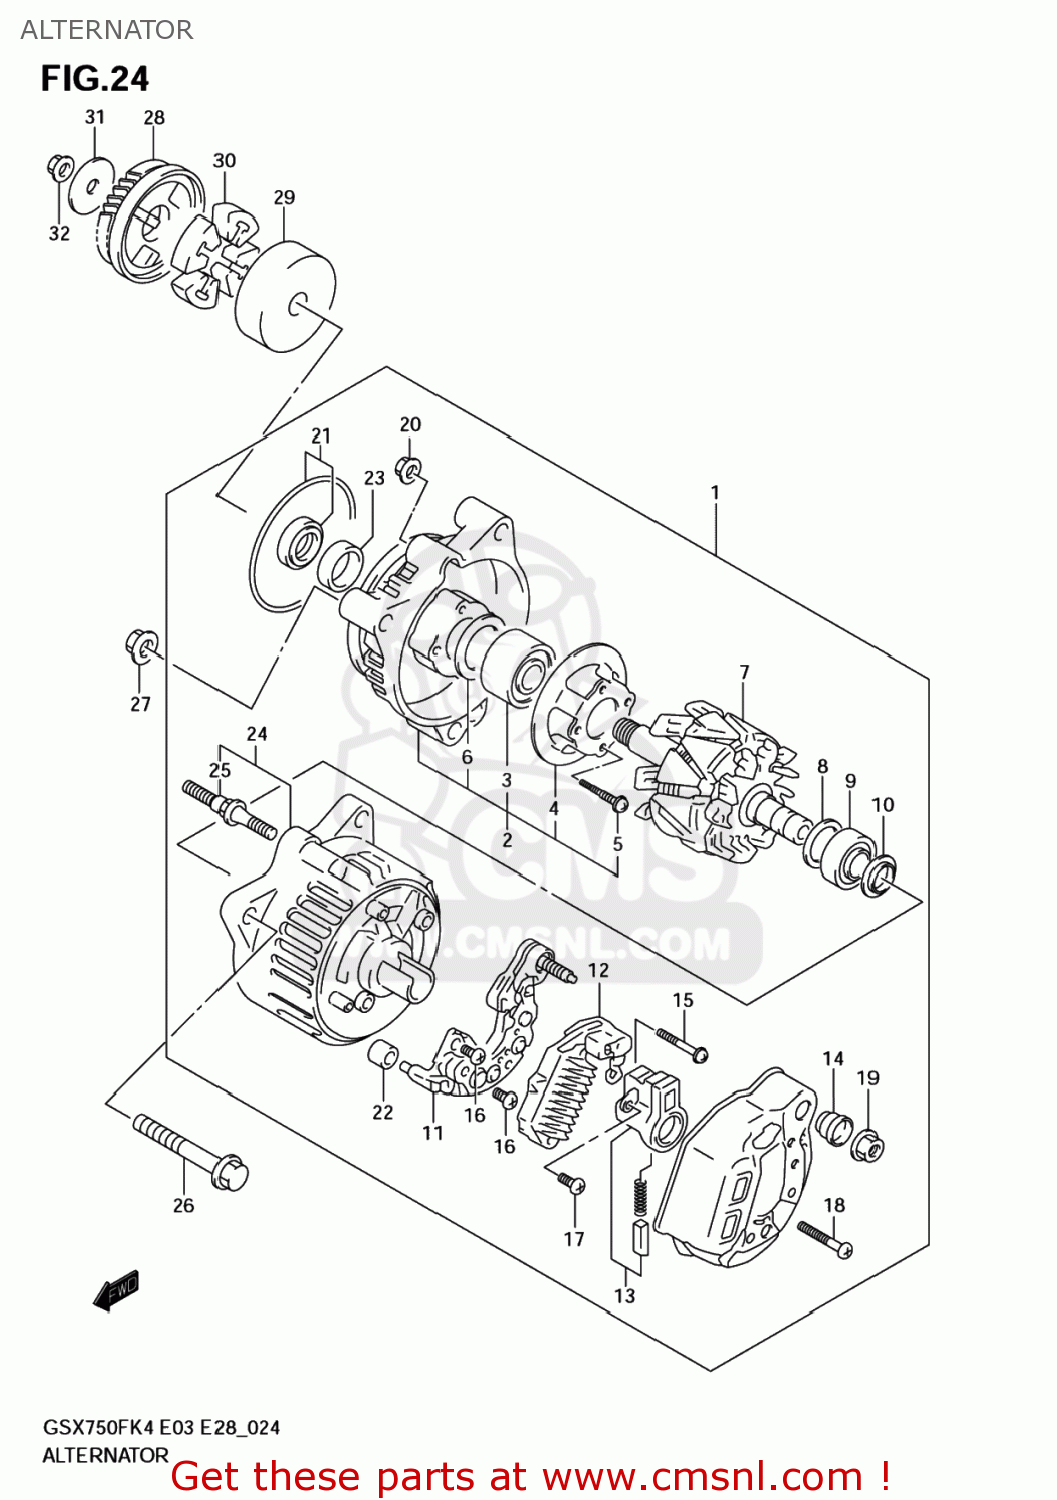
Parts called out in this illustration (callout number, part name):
1	ALTERNATOR ASSY
2	FRAME,DRIVE END
3	BEARING
4	RETAINER
5	SCREW(4X14)
6	COVER,BEARING
7	ROTOR ASSY
8	COVER,BEARING
9	BEARING
10	COVER(2)
11	HOLDER,RECTIFIER
12	REGULATOR ASSY
13	HOLDER,BRUSH
14	INSULATOR,TERMINAL
15	SCREW
16	SCREW 4X6
17	SCREW
18	SCREW
19	NUT
20	NUT
21	SERVICE KIT(A)
22	SERVICE KIT(B)
23	SPACER
24	FRAME,END
25	STUD BOLT
26	BOLT
27	NUT
28	GEAR,GENERATOR DRIVEN
29	HOUSING,GENERATOR GEAR DAMPER
30	DAMPER,GENERATOR DRIVEN
31	WASHER
32	NUT
